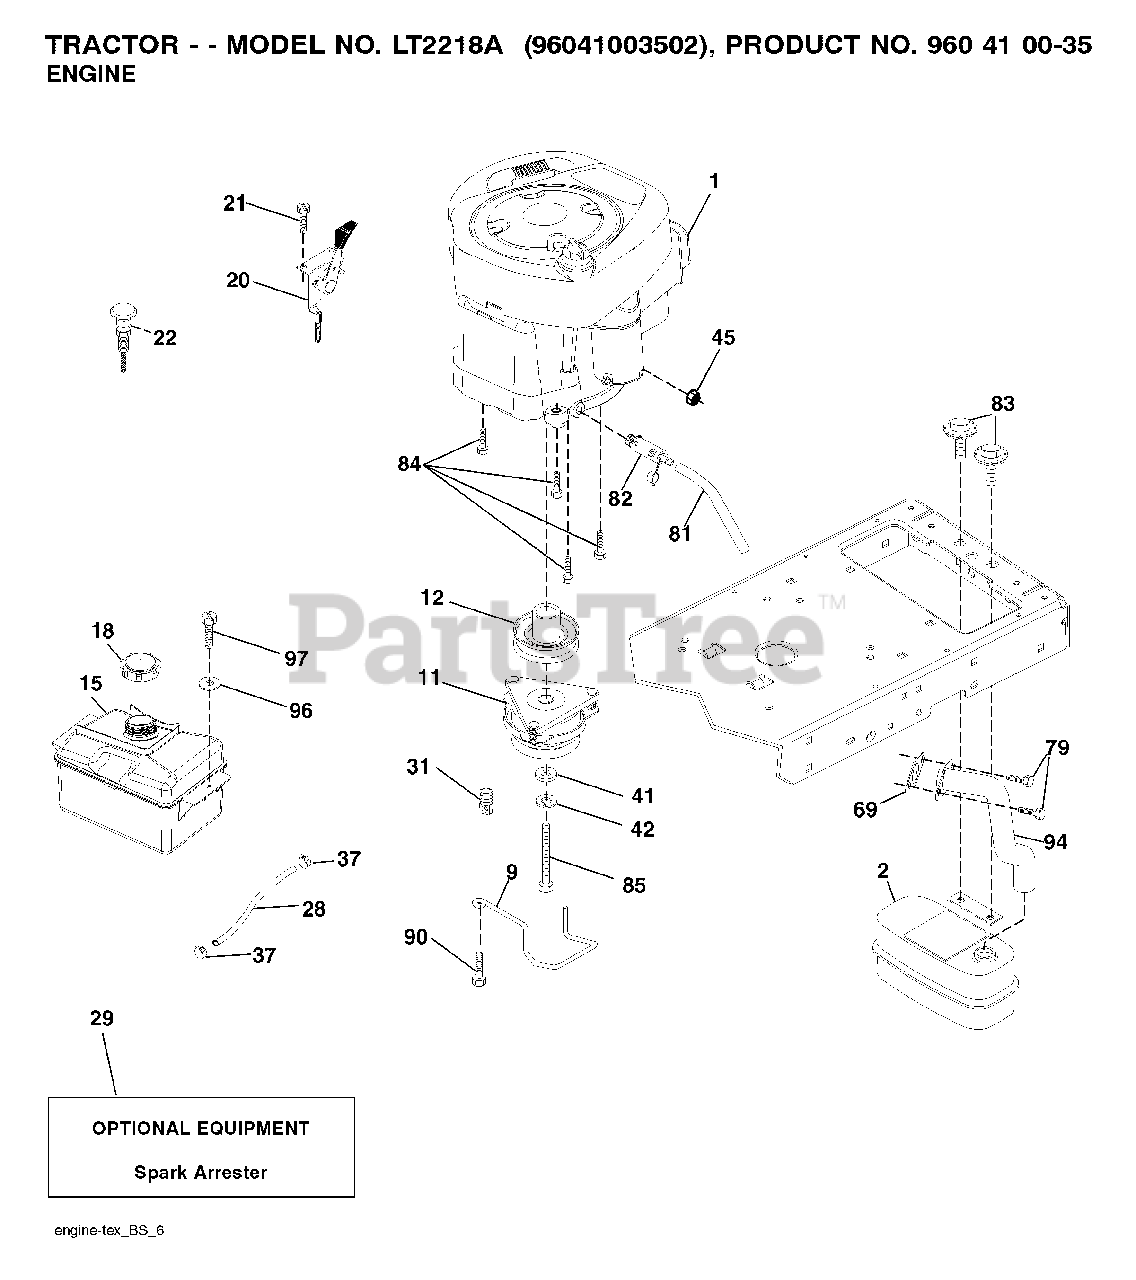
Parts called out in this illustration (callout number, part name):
2	MUFFLER.SINGLE.CYL.KOHL/B&S
9	KEEPER.BELT.ENGINE.4.2
11	CLUTCH
12	PULLEY.ENGINE.TUFFTORQ
15	FUEL TANK FRT 2 GAL.
18	FUEL CAP
20	CONTROL.TH/CK.C.
21	SCREW
28	LINE.FUEL.20
29	ARRESTER SPARK (OPTIONAL)
31	PUSH CLIP
37	HOSE CLAMP
42	LOCKWASHER
45	NUT
69	REPL BY 532 27 22-93
79	SCREW.SOCKET HD.5/16-1
81	TUBE, DRAIN OIL ASM.
82	PLUG DRAIN OIL EASY
83	BOLT, 5/16-18 X 1 3/4
84	SCREW.3/8-16
85	BOLT HEX 7/16-20X4-1/4"
90	SCREW 3/8-16X1
94	EXHAUST.TUBE.B&S.
97	SCREW HEXWSHR 1/4-20X3/4
102	SCREW
107	SCREW.1/4-20X5/8
